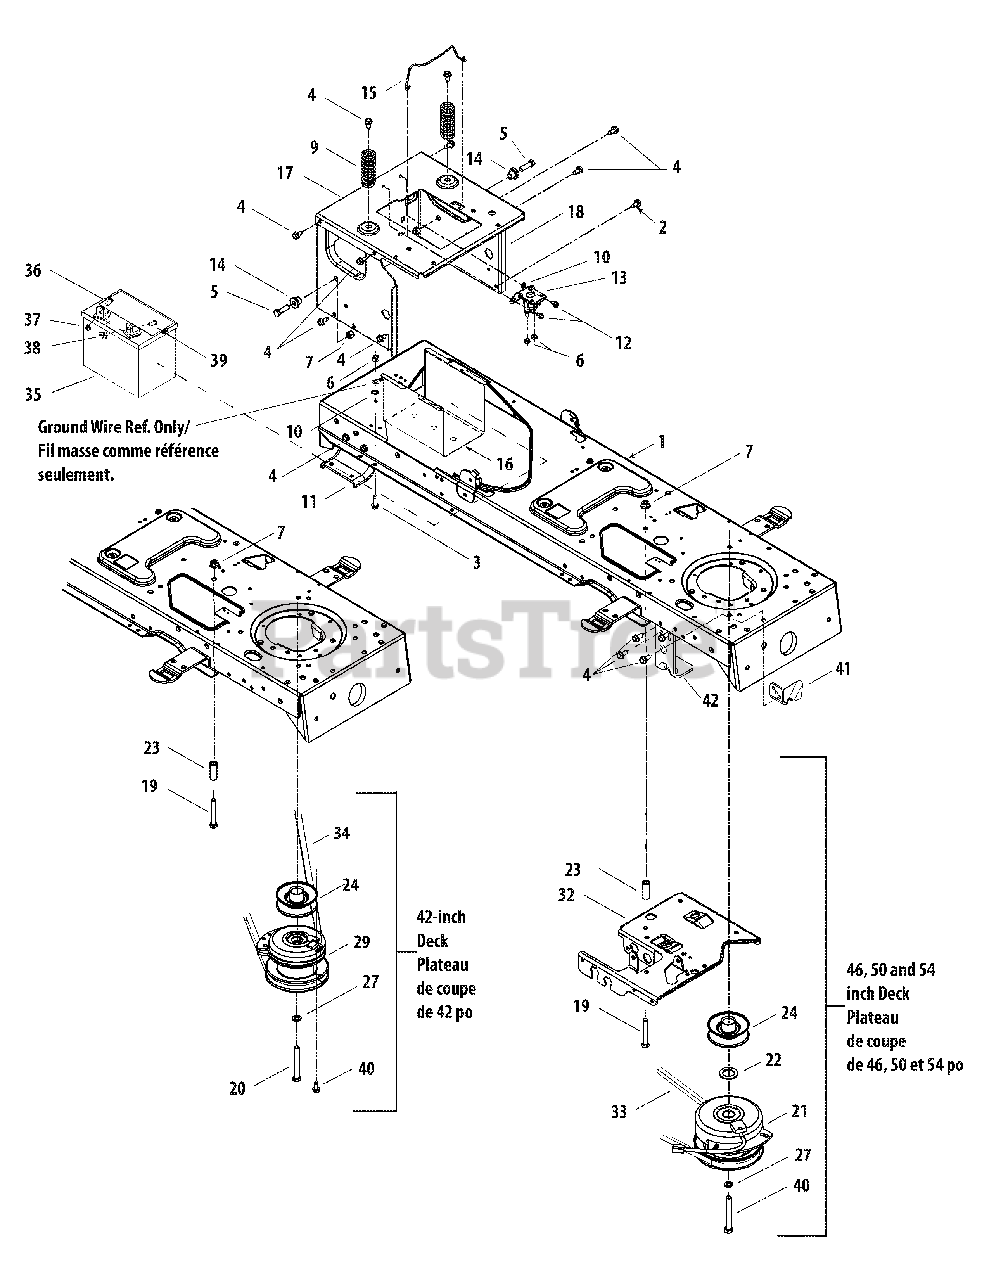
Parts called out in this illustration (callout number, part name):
3	Thd Forming Scr. 1/4-20 x .75 Lg.
4	S-Tapp Scr 5/16-18 x .75
5	Hex Bolt 3/8-16 x 1.25
6	Hex L-Flanged Nut 1/4-20 Gr. F Nylon
7	Flange Lock-Nut 3/8-16 Gr. F Nylon
9	Compression Spring 1.28 x 3.125
10	Ext. L-Washer 1/4 ID
12	Hex Wash S-Tapp Scr 1/4-20 x .50
13	Solenoid
14	Shoulder Spacer .38 x 1.0 x .70
15	Battery Retainer Rod
20	Hex Bolt 7/16-20 x 3.25 Gr. 5
21	Electric PTO Clutch 46 & 50" Deck
21	Electric PTO Clutch 54" Deck
22	Flat Washer 1.03 ID x 1.64 OD x .095
23	Spacer .385 ID x .635 OD x 1.54
24	Engine Pulley
24	Engine Pulley, 3.56 OD
27	Lockwasher 7/16 ID
29	Electric PTO Clutch 42" Deck
33	V-Belt Type A Sec x 118.20
33	V-Belt Type A Sec x 138.0
33	V-Belt 90.8
34	PTO Belt
35	Battery 245 CCA (Dry)
36	Hex Flg. Bolt 1/4-10 x .75 Gr. 5
37	Sems Hex Nut 1/4-20
38	Wing Nut 1/4-20 Thd.
39	Shoulder Screw, 1/4-20
40	Hex Hd. Cap Scr. 7/16-20 x 3.5
